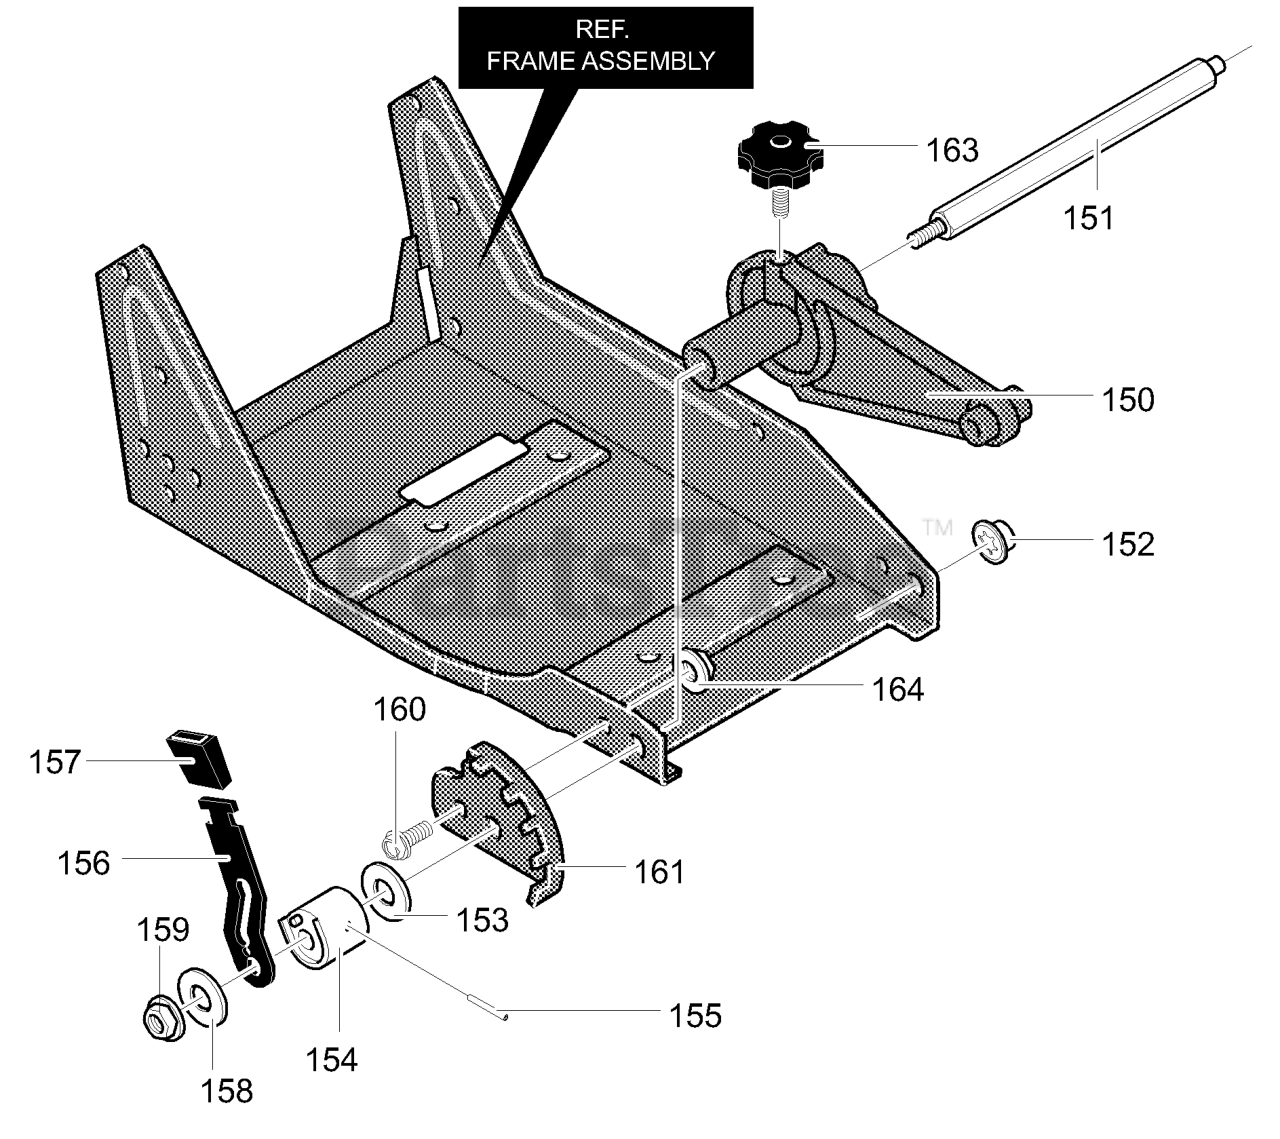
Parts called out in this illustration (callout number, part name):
150	Front Wheel Arm
151	Front Mount Curb Rod
152	Pushnut, Washer
153	Plastic Washer
154	Spacer, Height Adjust
155	Pin, Spring
156	Lever, Height Adjust
157	Knob, Rectangle
158	Flatwasher
160	Screw, 5/16-18 x 0.63
161	Plate, Height Adjust
163	Knob, Molded
164	Nut, 5/16-18
